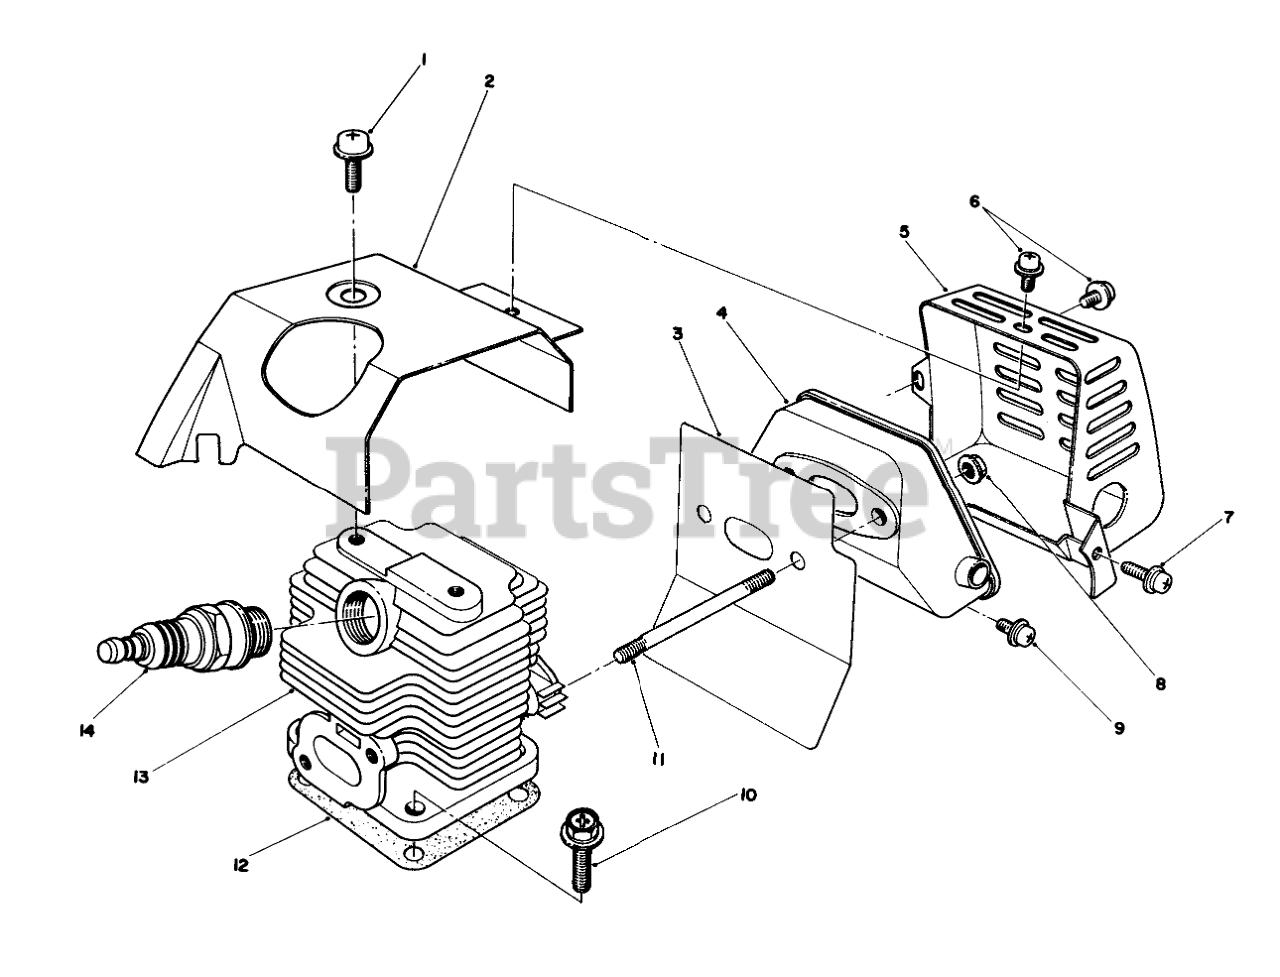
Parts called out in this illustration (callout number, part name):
1	Screw & Dishes
2	CYLINDER COVER
3	Gasket-Muffler
4	MUFFLER
5	COVER, MUFFLER
6	Screw & Washer
7	Screw & Washer
8	NUT, FLANGE
9	Screw & Washer
10	BOLT AND WASHER
11	Bolt-Stud
12	CYLINDER GASKET
13	Cylinder (Incl. Ref. #11)
14	SPARK PLUG (NGK)
